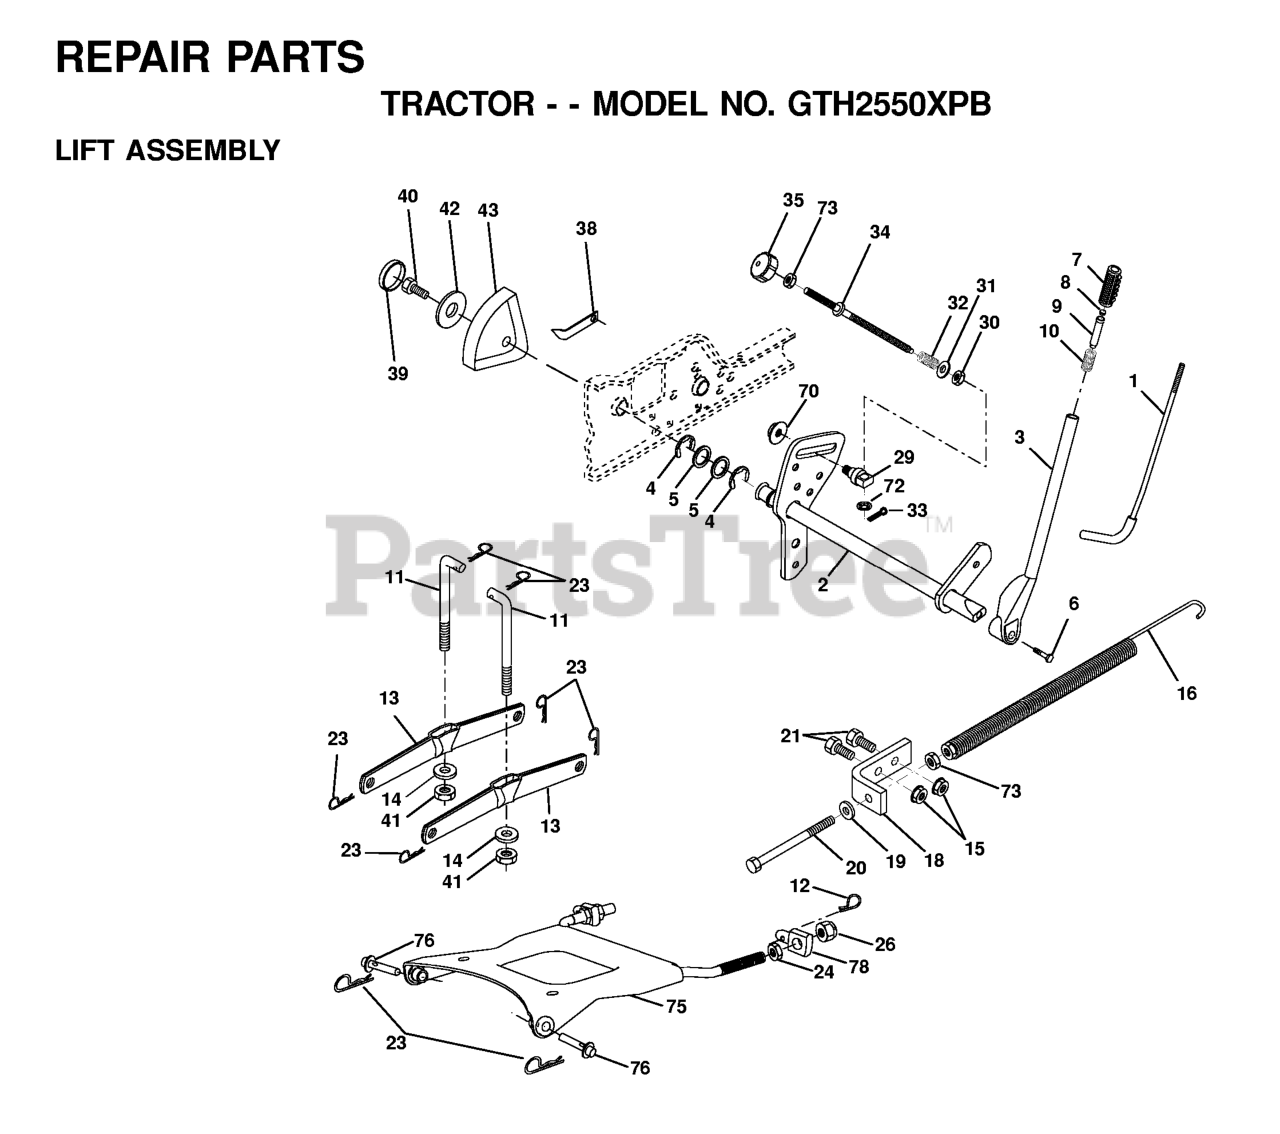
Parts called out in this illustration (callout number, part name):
1	LEVER ROD LT
3	LEVER ASSY-LIFT RH
5	Washer 29/32 x 1 - 1/4 x 16 Ga.
6	Bolt, Fin Hex 3/8-16 x 1-1/12
7	GRIP HANDLE
8	PLUNGER BUT KIT
9	PLUNGER BUT KIT
10	SPRING**
11	LINK LIFT
12	SPRING RETAINER
13	ARM.REAR.SUSPENSION
14	BEARING.PIVOT.LIFT
16	LIFT SPRING
19	WASHER
21	BOLT
23	RETAINER-SPRNG RB
24	NUT.HEX.JAM.1/2-13
26	NUT.LK.W/WSH.1/2.
32	SPRING.COMP.INF.H
33	COTTER PIN
34	ROD.LIFT.ADJUSTABLE
35	KNOB INF 3/8-16
38	POINTER, HEIGHT INDICATOR(2 2)
40	SCREW 5/16-18X1
41	NUT CROWNLOCK 3/8-24
43	HEIGHT INDICATOR
70	NUT
72	NUT PUSH M
73	NUT
75	PLATE ASM SUSP FRONT
76	PIN.FLANGE
